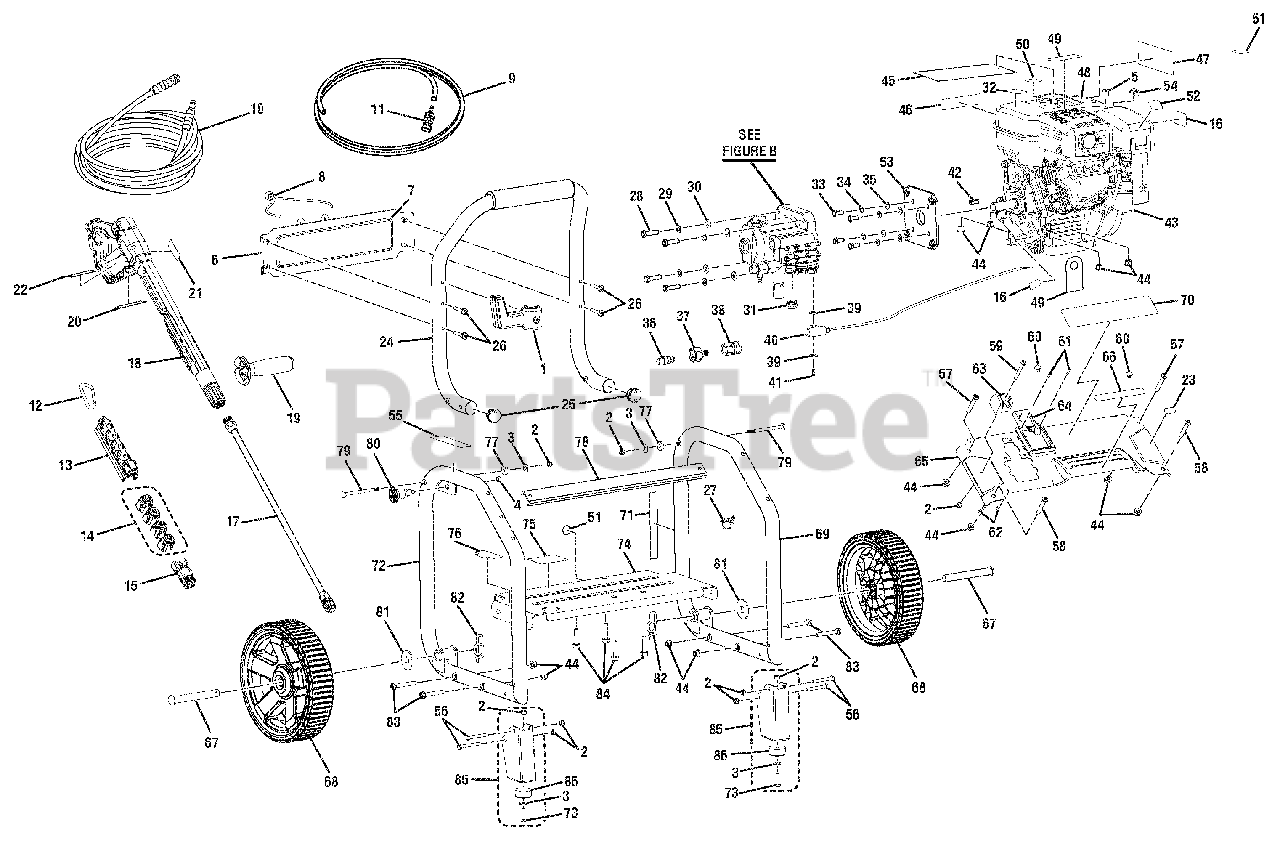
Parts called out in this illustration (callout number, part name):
1	Wand Holder Assembly
2	Lock Nut (1/4-20)
3	Washer (1/4 in.)
4	Lock Nut (1/2-20)
5	Swivel Bushing
6	Logo Plate
7	Performance Label
8	Bungee Cord and Bead Assembly
9	Injection Hose
10	High Pressure Hose (30 ft.)
11	Injection Hose Filter
12	Spring Clip
13	Storage Holder
14	Nozzle Kit
15	Soap Blaster Nozzle
16	Squeeze Trigger Label
17	Spray Wand
18	Trigger Handle Assembly (Inc. Key Nos. 19-22)
19	Auxiliary Handle Assembly
20	Trigger Guard Warning Label (French/Spanish)
21	Trigger Guard Warning Label (English)
22	Max Pressure Label
23	Idle Control Label
24	Handle Assembly (Inc. Key No. 25)
25	Handle Tube Cap
26	Bolt (1/4 x 42 mm, Pan Hd.)
27	Cable Clamp
28	Bolt (3/8-16 x 1-3/8 in., Hex Hd.)
29	Lock Washer (3/8 in.)
30	Washer (3/8 in.)
31	Threaded Valve Plug
32	Do Not Mix Label
33	Bolt (5/16-24 x 3/4 in., Hex Hd.)
34	Lock Washer (5/16 in.)
35	Washer (5/16 in.)
36	Thermal Release Valve
37	Garden Hose Coupler w/Filter
38	Quick Disconnect (Female)
40	Throttle Control Assembly
41	Throttle Control Bolt (Special)
42	Output Shaft Key (27 mm)
43	SP170 Hori. Engine (CARB, GV80991, 2012)
44	Lock Nut (M8 x 1.25 mm)
45	Hang Tag (Engine)
46	Add Lubricant Label
47	Combustion Warning Label
48	Danger Label (English)
49	Oil Dipstick Hang Tag
50	E-85 Label
51	Check Oil Label
52	Hot Muffler Label
53	Pump Flange
54	Cable Clamp
55	Handle Release Label
56	Bolt (1/4-20 x 52 mm, Hex Hd.)
57	Bolt (M8 x 50 mm, Hex Soc. Hd.)
58	Bolt (M8 x 46 mm, Hex Soc. Hd.)
59	Screw (1/4-20 x 2.1 in., T30, Torx Hd.)
60	Bumper Handle
61	Screw (M4 x 12 mm, Hex Button Hd.)
62	Lock Nut (M4)
63	Wand Holder
64	Trigger Handle Storage
65	Face Plate
66	Hot Surface Label
69	Left Frame
70	Logo Label
71	Quick Start Label (Engine)
72	Right Frame Assembly
73	Bolt (1/4-20 x 1 in.)
74	Engine Plate
75	Data Label (GV80991)
76	Quick Start Label (Pump)
77	Washer (OD20 x ID8 x 4.5t)
79	Connector Pin (1/4 in.)
80	Handle Knob
81	Washer (5/8 in.)
82	Hitch Pin
83	Bolt (M8 x 55 mm, Hex Hd.)
84	Bolt (M8 x 45 mm, Hex Hd.)
85	Foot Assembly (Inc. Key Nos. 2-3 and 86-87)
86	Wear Pad
